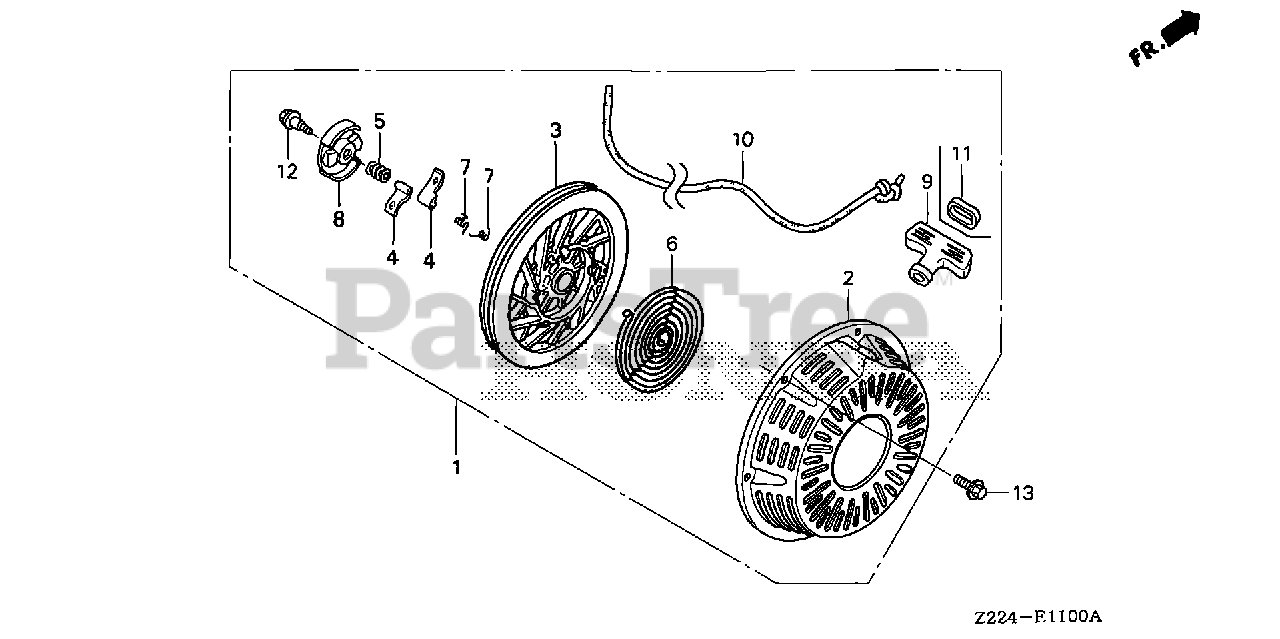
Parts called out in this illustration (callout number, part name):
1	STARTER ASSY., RECOIL *NH1* (BLACK)
2	CASE, RECOIL STARTER *NH1* (BLACK)
3	PULLEY, RECOIL STARTER
4	RATCHET, STARTER
5	SPRING, FRICTION
6	SPRING, STARTER RETURN
7	SPRING, RATCHET
8	RETAINER, SPRING
9	GRIP, STARTER (FOR U.S.A.)
10	ROPE, RECOIL STARTER
11	REINFORCEMENT, GRIP
12	SCREW, CENTER
13	BOLT, FLANGE (6X10)
